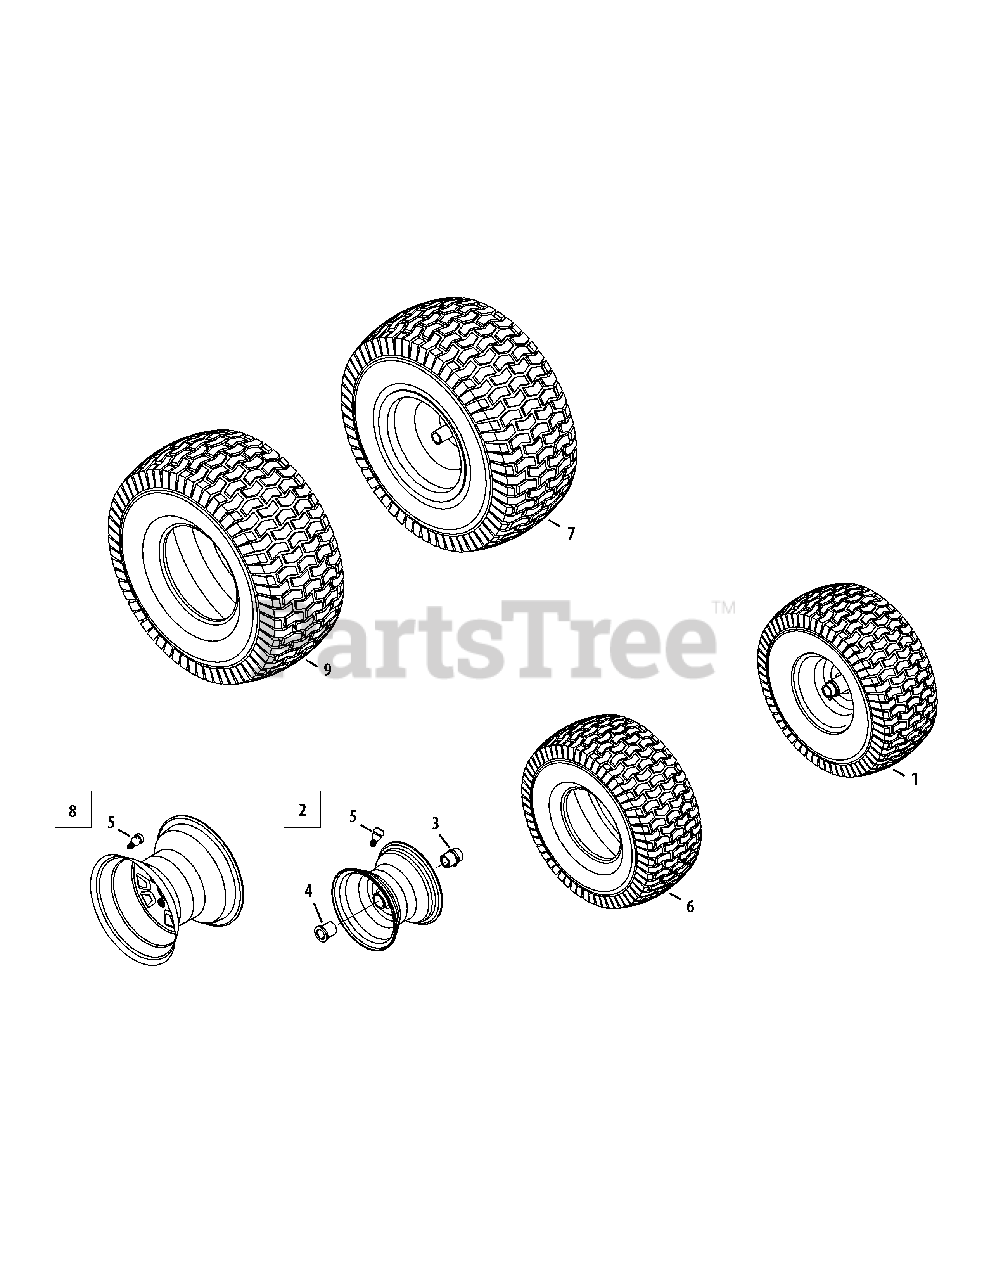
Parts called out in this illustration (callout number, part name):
1	Wheel Ass’y, Complete, 16 x 6 x 5.8
2	Rim Ass’y, 8.0 x 5.3, w/Flange Bearings
3	Bearing, Flange, .760 ID w/ Fitting
4	Bearing, Flange, .760 x 1.00 x 1.20
5	Valve, Tubeless Air
6	Tire, 16 x 6.5 x 8 Sq Shoulder
7	Wheel, Complete, 22 x 9.5 x 12
8	Rim Ass’y, 12.0 x 7.0
9	Tire, 22 x 9.5 x 12 Sq Shoulder
